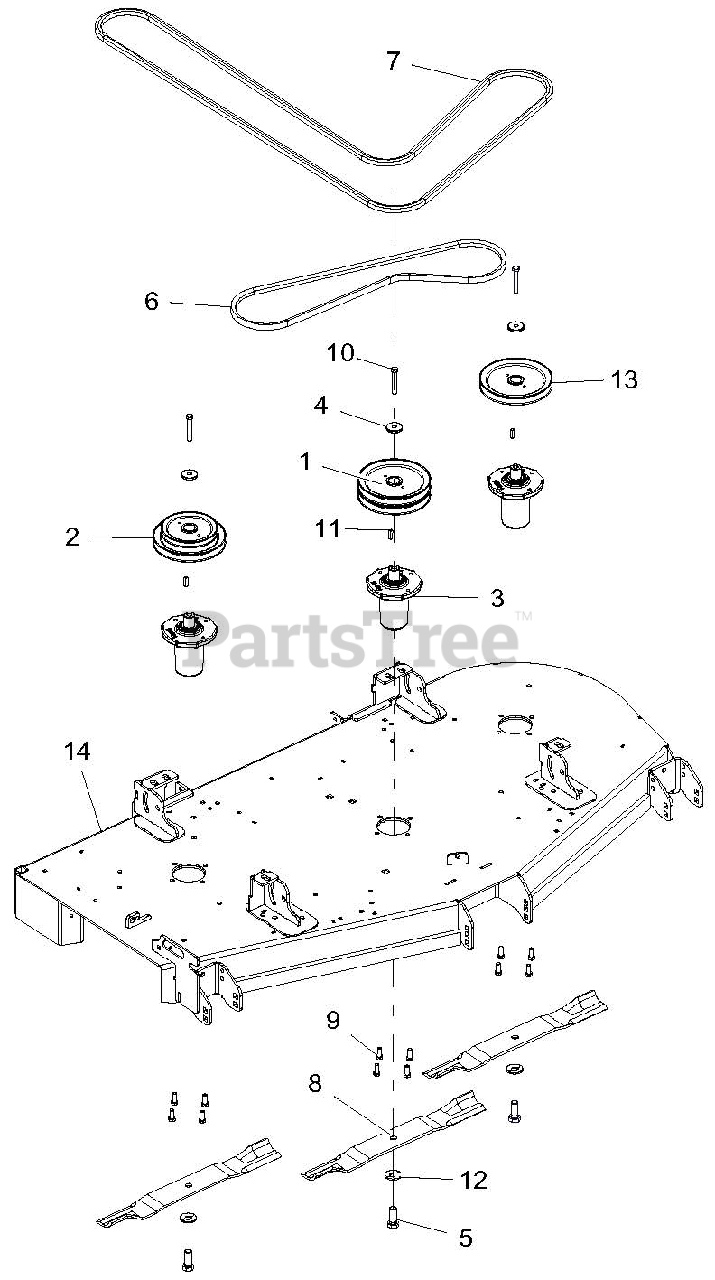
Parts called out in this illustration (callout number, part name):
1	PULLEY, DOUBLE 1"ID X 6.75"OD-BLACK
2	PULLEY, DOUBLE -1" ID X 6.75" & 5.25" OD
3	SERVICE, ASM SPINDLE- DUCTILE
4	RETAINER, SHEAVE SPINDLE
5	BLT, HEX .62-18X1.75 GR8 YWZC
6	BELT, B 63.00 RAW COGGED
7	BELT, BB 118.00 WRAPPED HEX
8	BLADE, MOWER 60"
9	BLT-HEX .38-16X1.00 GR5 YWZC EP30
10	BLT-HEX .38-16X2.75 GR8 YWZC
11	KEY-SQ .250X.250X1.00 RC 40-50
12	WSHR, BLVL .63X1.625X.14
13	PULLEY, V-1" ID X 6.75" OD-BLACK
14	WLDMT, 60" SIDE DISCH DECK
